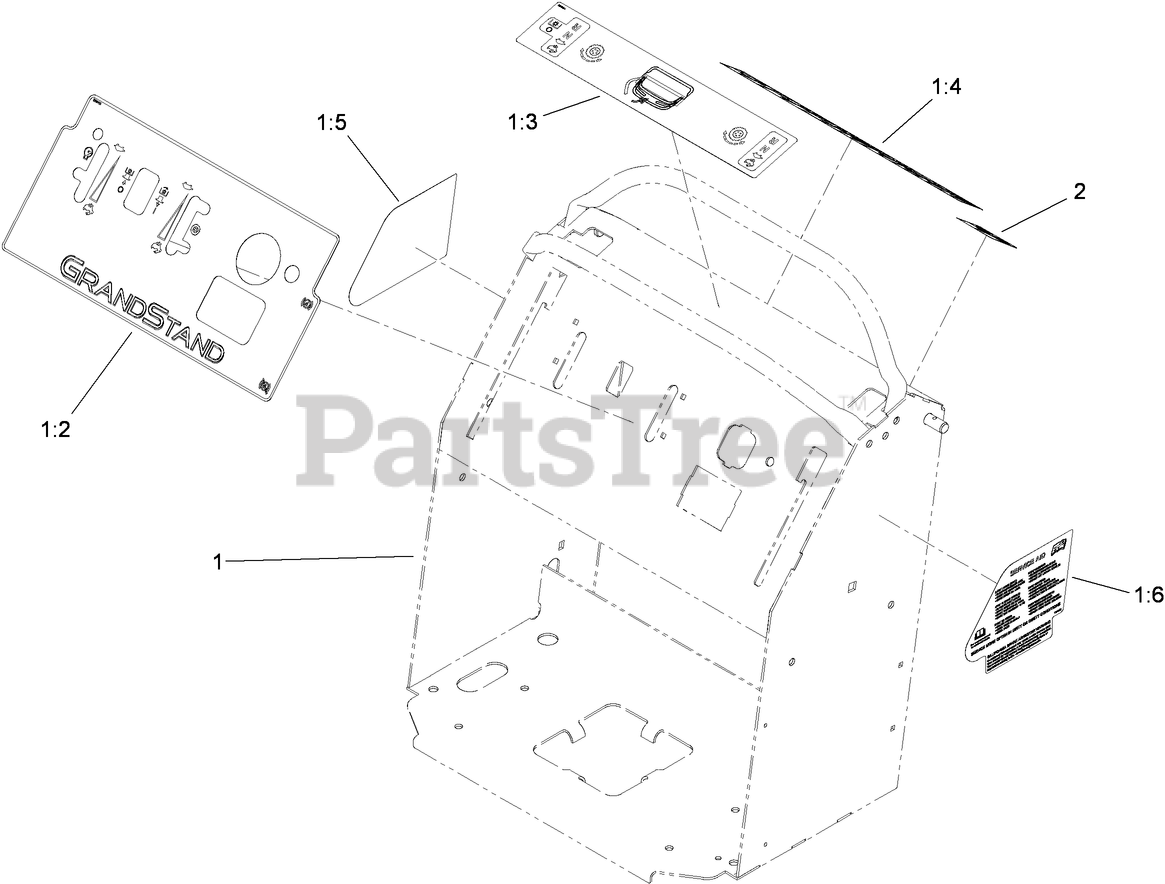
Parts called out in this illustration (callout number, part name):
1	CONTROL TOWER ASM
1:2	DECAL-PANEL, CONTROL
1:3	DECAL-OPC
1:4	DECAL-WARNING
1:5	DECAL-HOC
1:6	DECAL-AID, SERVICE
2	DECAL-STABILITY
